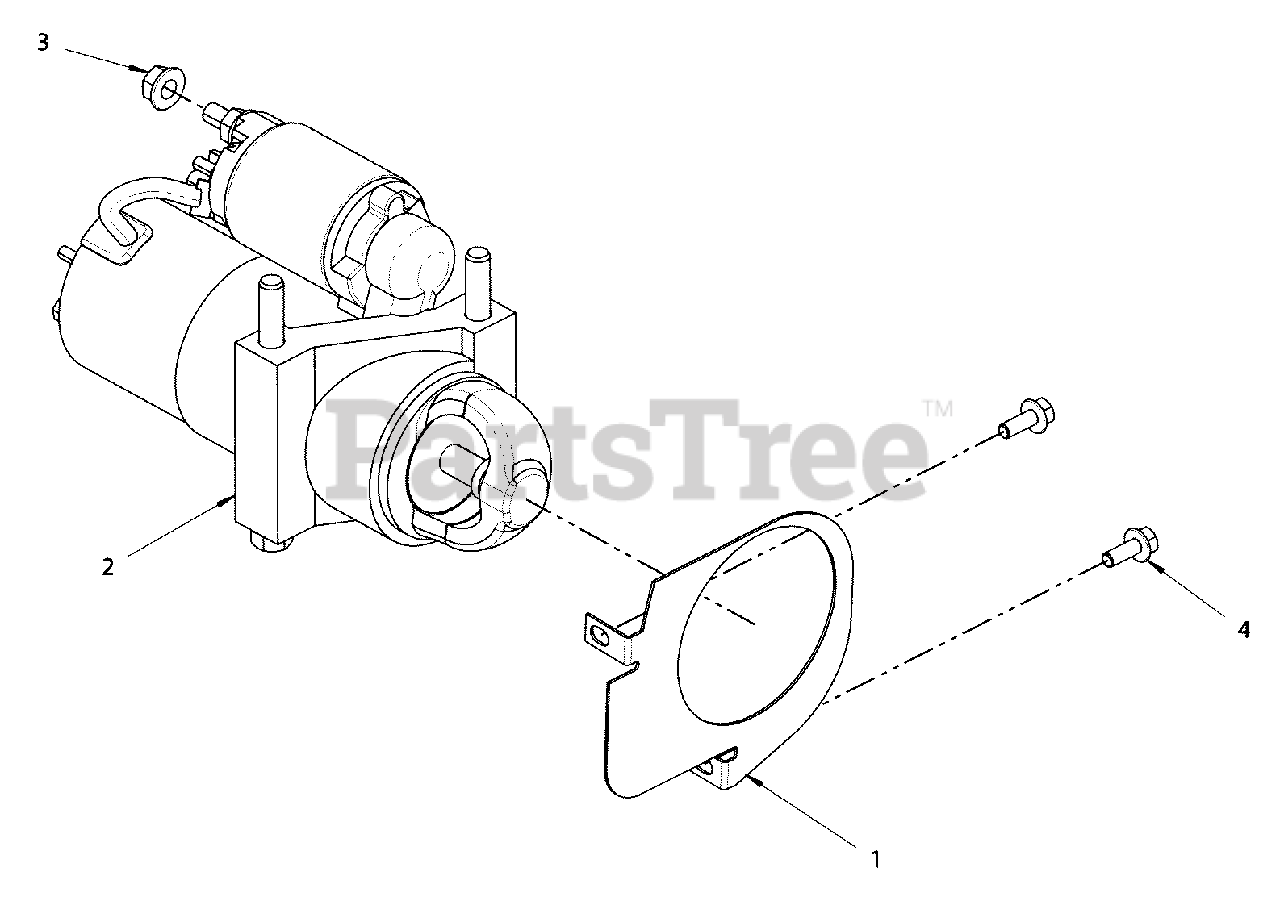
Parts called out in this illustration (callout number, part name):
1	COVER, STARTER MOUNT
3	NUT, FLANGE
4	BOLT
